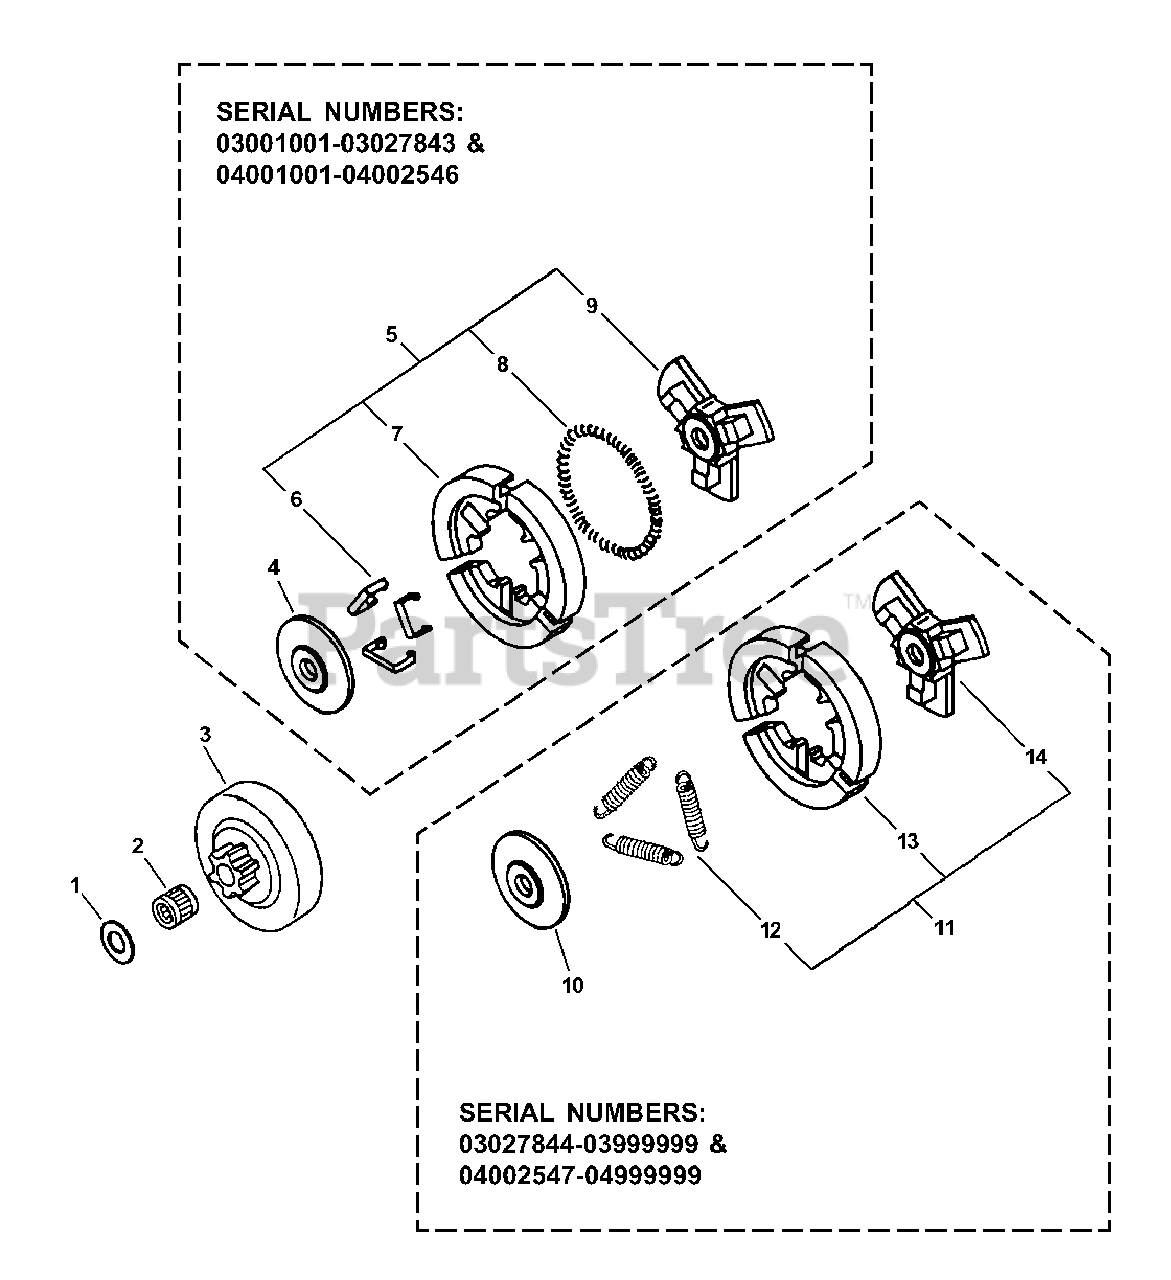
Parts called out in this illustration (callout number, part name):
2	BEARING, NEEDLE
3	DRUM, CLUTCH
4	PLATE, CLUTCH
5	CLUTCH ASSY
6	CLIP, SPRING
7	CLUTCH SHOE SET
8	SPRING, CLUTCH
9	HUB, CLUTCH
10	PLATE, CLUTCH
11	CLUTCH ASSY
12	SPRING, CLUTCH
13	CLUTCH SHOE SET
14	HUB, CLUTCH
